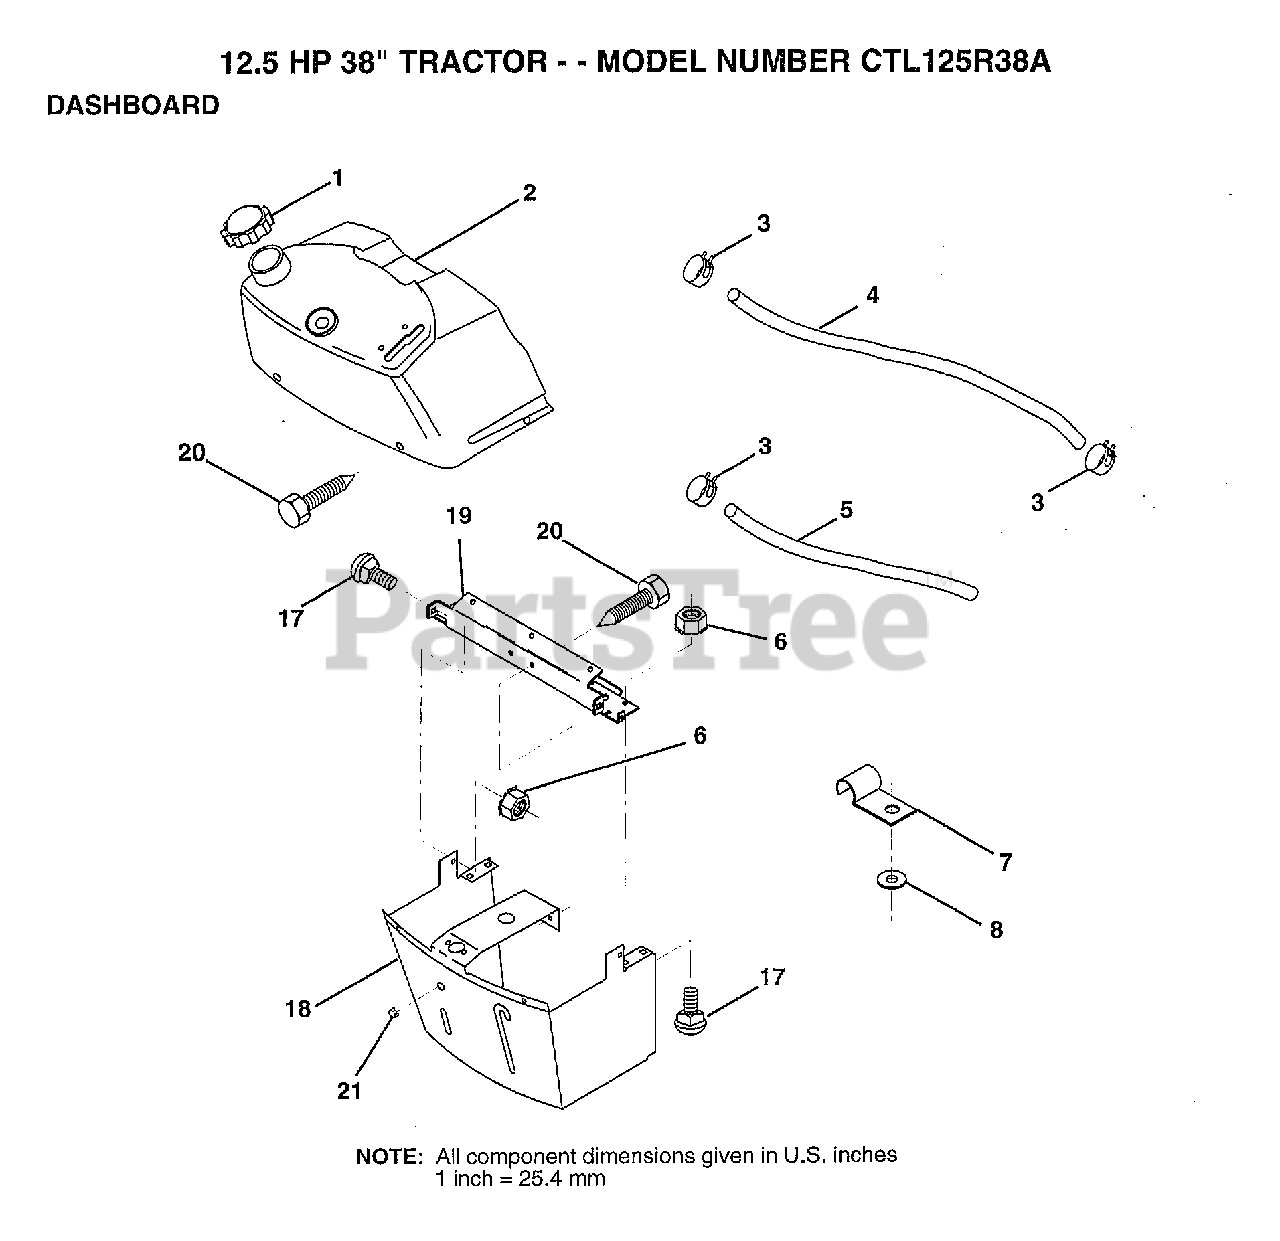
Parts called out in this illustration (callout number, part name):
1	CAP.FUEL.N/VENT
2	TANK.ASM.DASH.LR
3	HOSE CLAMP
5	FUEL LINE T
6	NUT
7	CLIP T
8	WASHER PM
17	BOLT
18	SUPT ASM DASH
19	CROSS BRACE
20	SCREW.1/4-20X1/2
21	PLUG DOME
